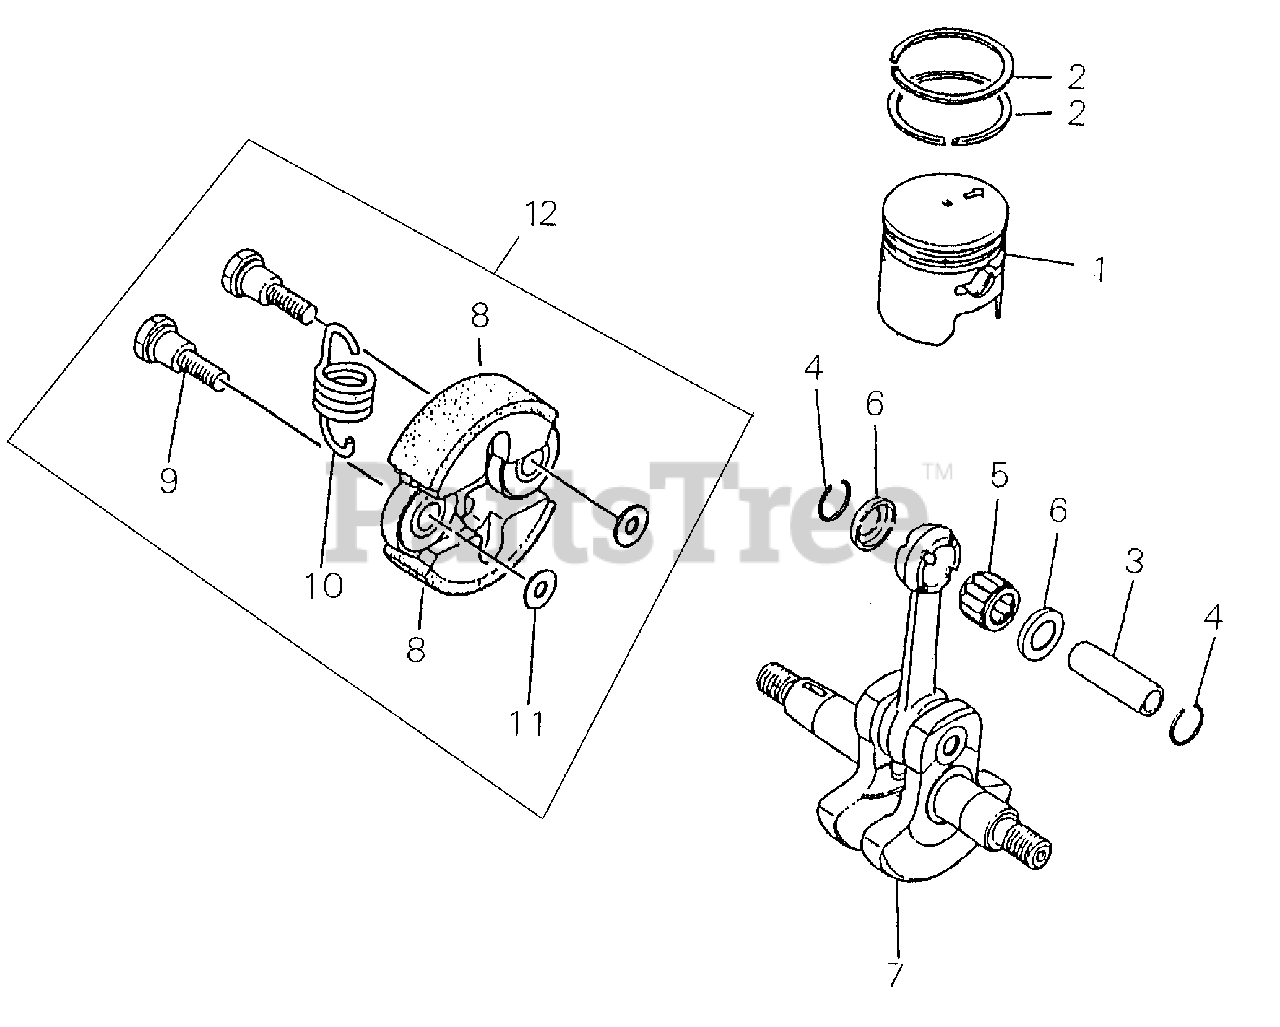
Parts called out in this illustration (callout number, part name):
1	PISTON
2	RING, PISTON
3	PIN, PISTON
4	RING, SNAP
5	BEARING, NEEDLE
6	WASHER, THRUST 9
7	CRANKSHAFT ASSY
8	SHOE, CLUTCH
9	BOLT, CLUTCH
10	SPRING, CLUTCH
11	WASHER 6 MM
12	CLUTCH ASSY
